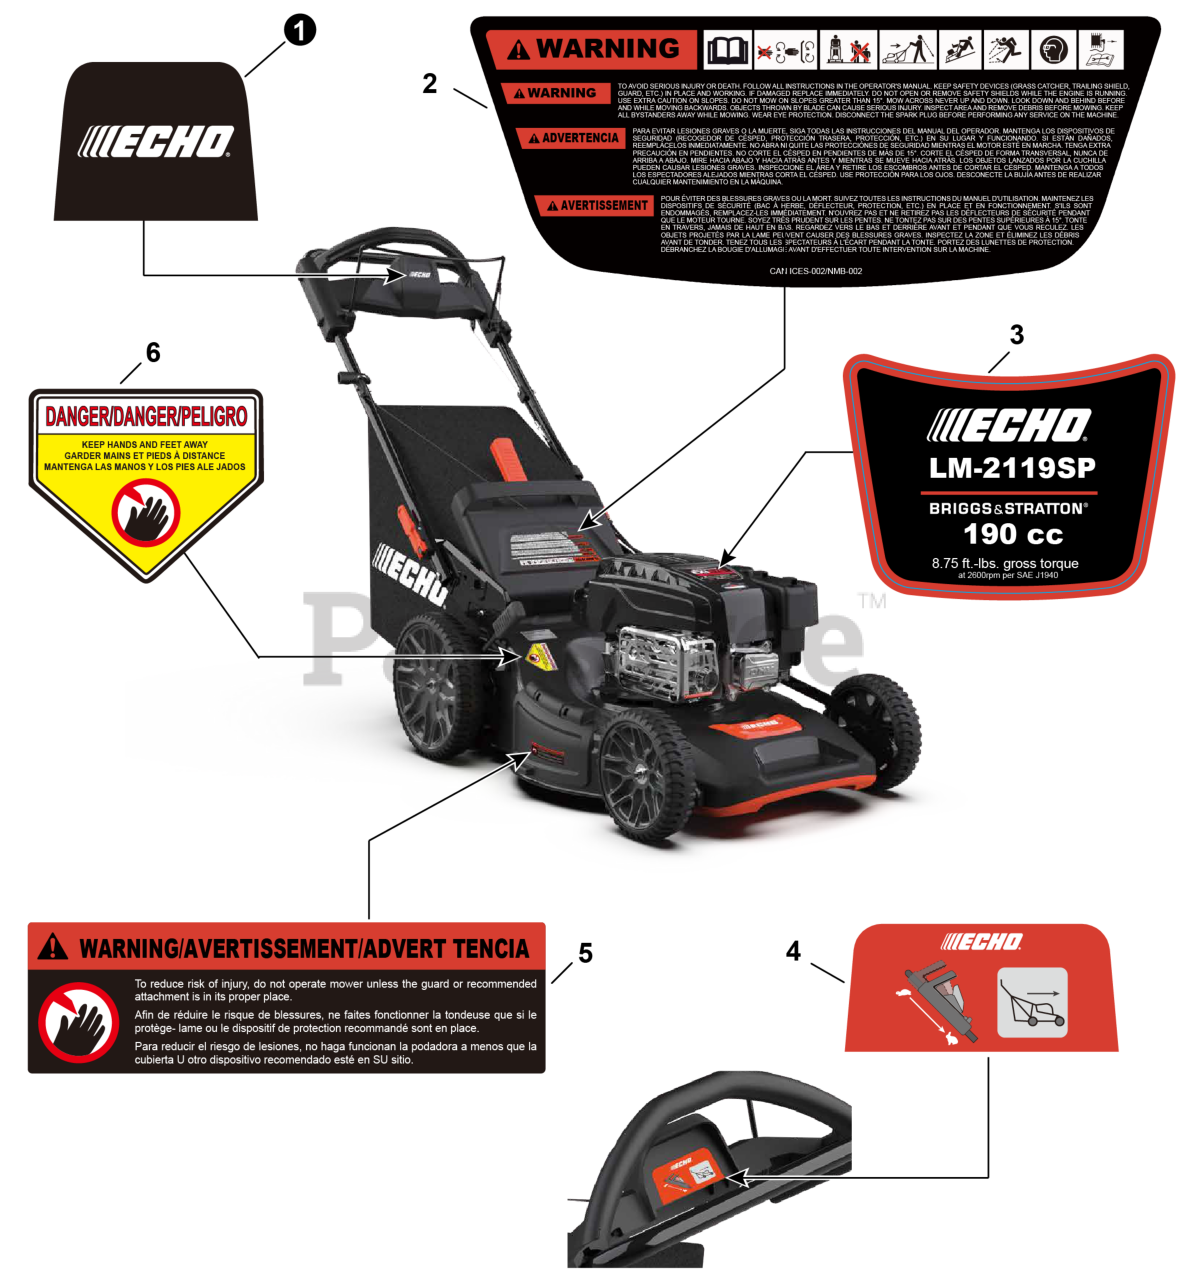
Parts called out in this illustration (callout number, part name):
1	LABEL, BRAND
2	LABEL, REAR COVER WARNING
3	LABEL, MODEL
4	LABEL, SELF-PROPEL
5	LABEL, WARNING
6	LABEL, DANGER
